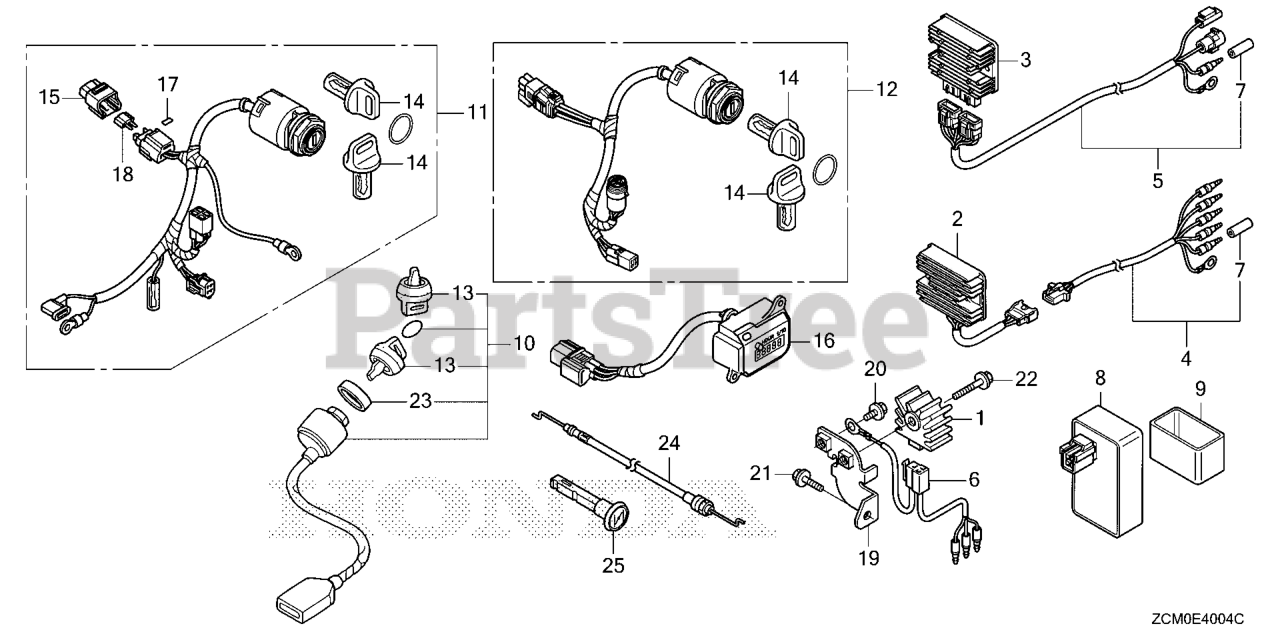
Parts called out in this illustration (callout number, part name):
1	RECTIFIER, REGULATOR (5A)
6	HARNESS ASSY., REGULATOR RECTIFIER
8	CONTROL UNIT, VALVE
9	CUSHION, VALVE CONTROL UNIT
